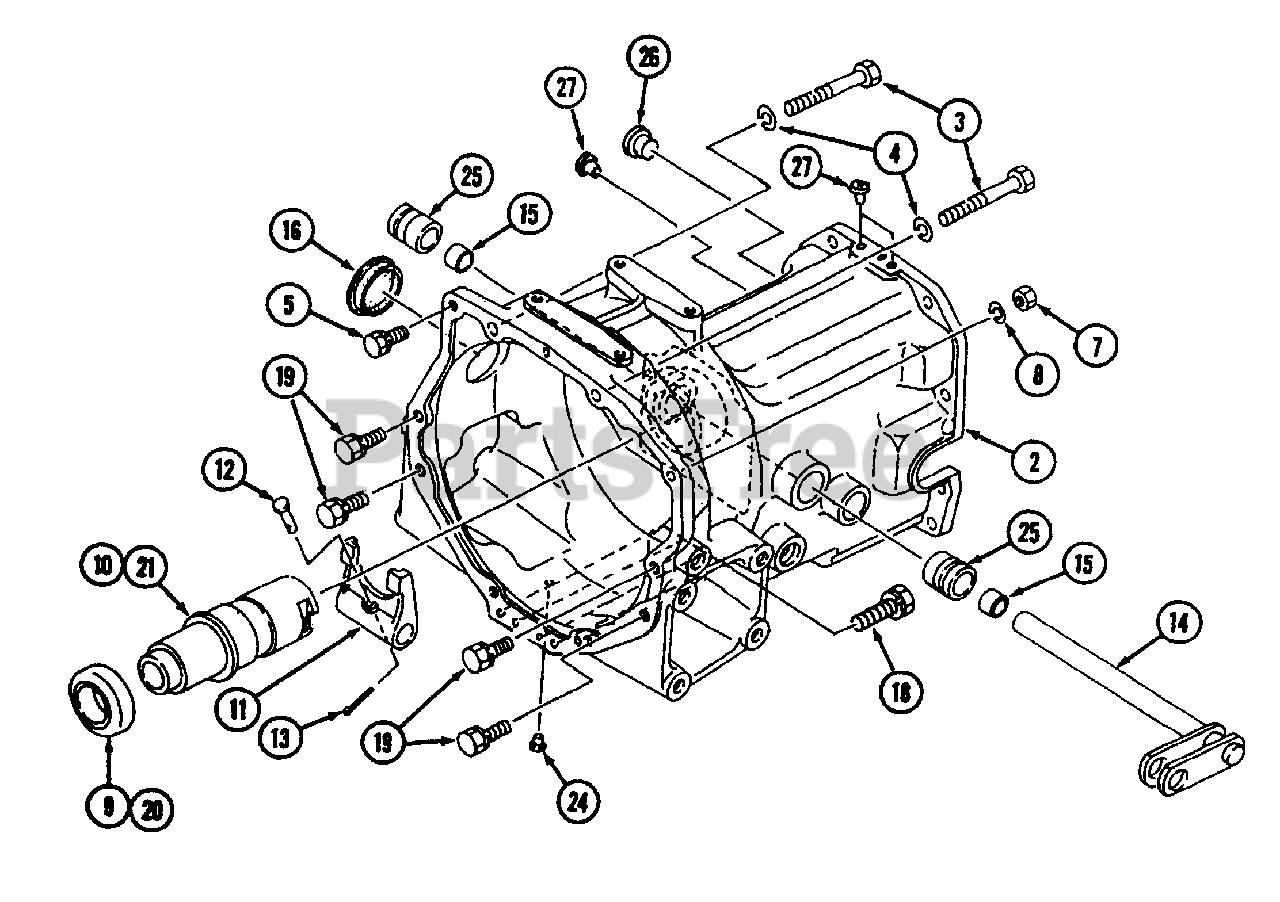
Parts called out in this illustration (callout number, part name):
2	Housing, Clutch
9	Bearing, Release (Gear)
10	Hub, Release (Gear)
11	Lever, Release
13	Pin, Split
14	Shaft, Release
20	Bearing, Release (HST)
21	Hub, Release (HST)
26	Plug (HST)
